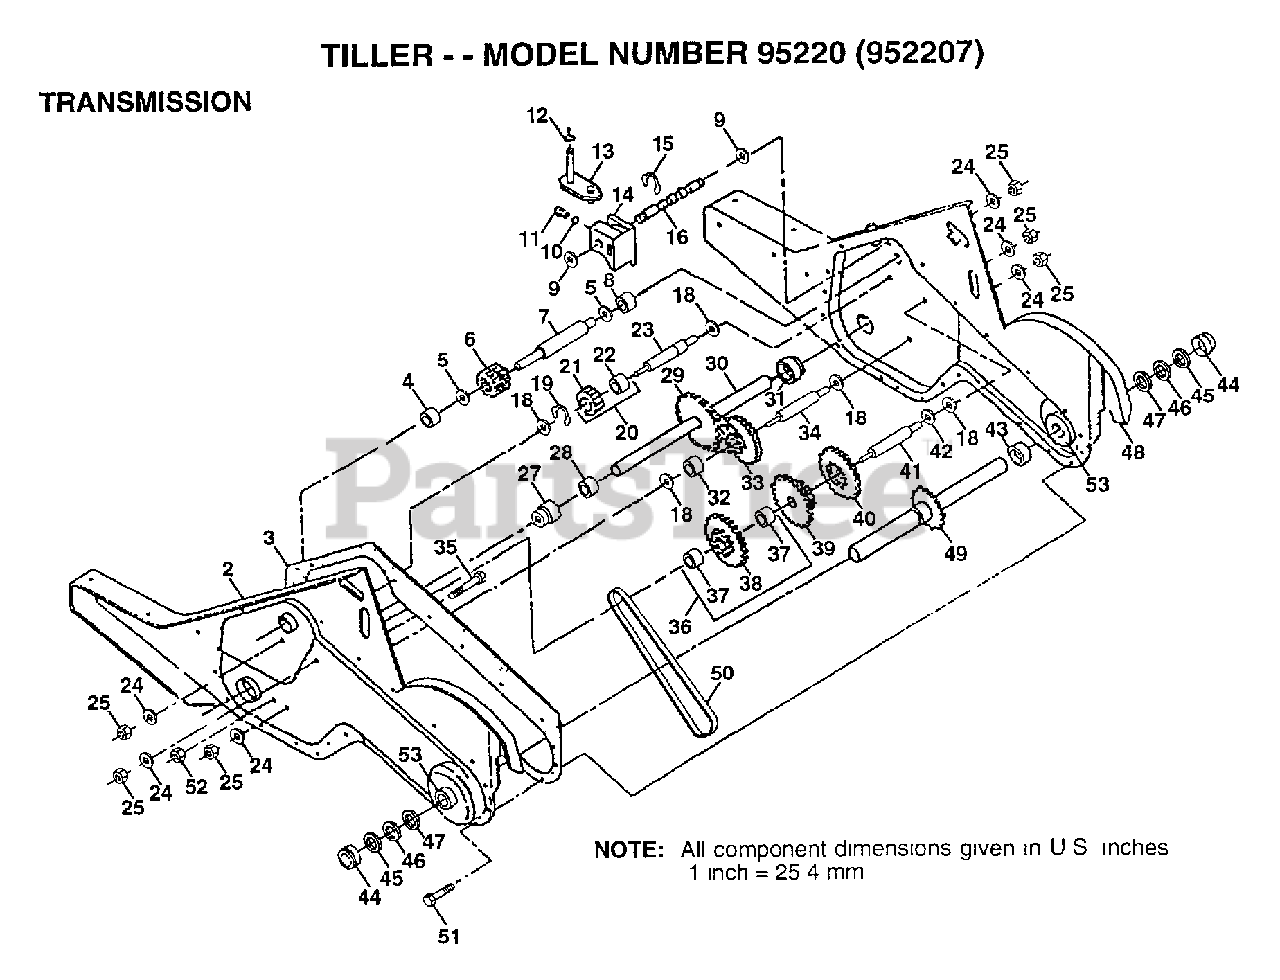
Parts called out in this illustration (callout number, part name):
1	Transmission Assembly
2	GEARCASE LH W/BRG
3	GASKET TI
4	NEEDLE BRNG LT
5	"T, BEARING"
6	GEAR PINION INPUT
7	"SHAFT.INPUT.""D"""
8	"TI, BEARING"
9	WASHER SEAL CRT
11	SPRING-SHIFT CRT
12	O-RING TI
13	BRACKET ASM SHIFT
14	SHIFT FORK TI
15	KLIP RING
16	SHAFT.SHIFT.4.250
18	WASHER
19	KLIP RING
20	GEAR ASSY CRT
21	GEAR-REV IDLR CRT
22	NEEDLE BEARING TI
23	SHAFT CRT
24	LOCKWASHER
25	NUT.ASF.HEX.7/16
27	BEARING.SHAFT.LH.
28	BUSHING TI
29	CHAIN CRT
30	GROUND SHAFT ASSY
31	BEARING.SHAFT.RH.
32	SPACER TI
33	SPRCKT 8 GEAR CRT
34	SHFT 2ND RED. CRT
35	SCRW WHIZ LOK CRT
36	SPROCKET ASM.
37	BEARING
39	GEAR TI
40	GEAR TI
41	REDUCTION SHFT TI
42	BRNG RACE
43	SPACER TI
44	CUP.FORMED.
45	RING SPIRAL CRT
46	SEAL RING RUBBER
47	OIL SEAL STD
48	GEARCASE RH W/BRG
49	TINE SHAFT
50	CHAIN.50 LINK TI
51	SCREW
52	NUT.HEX.5/16-18
